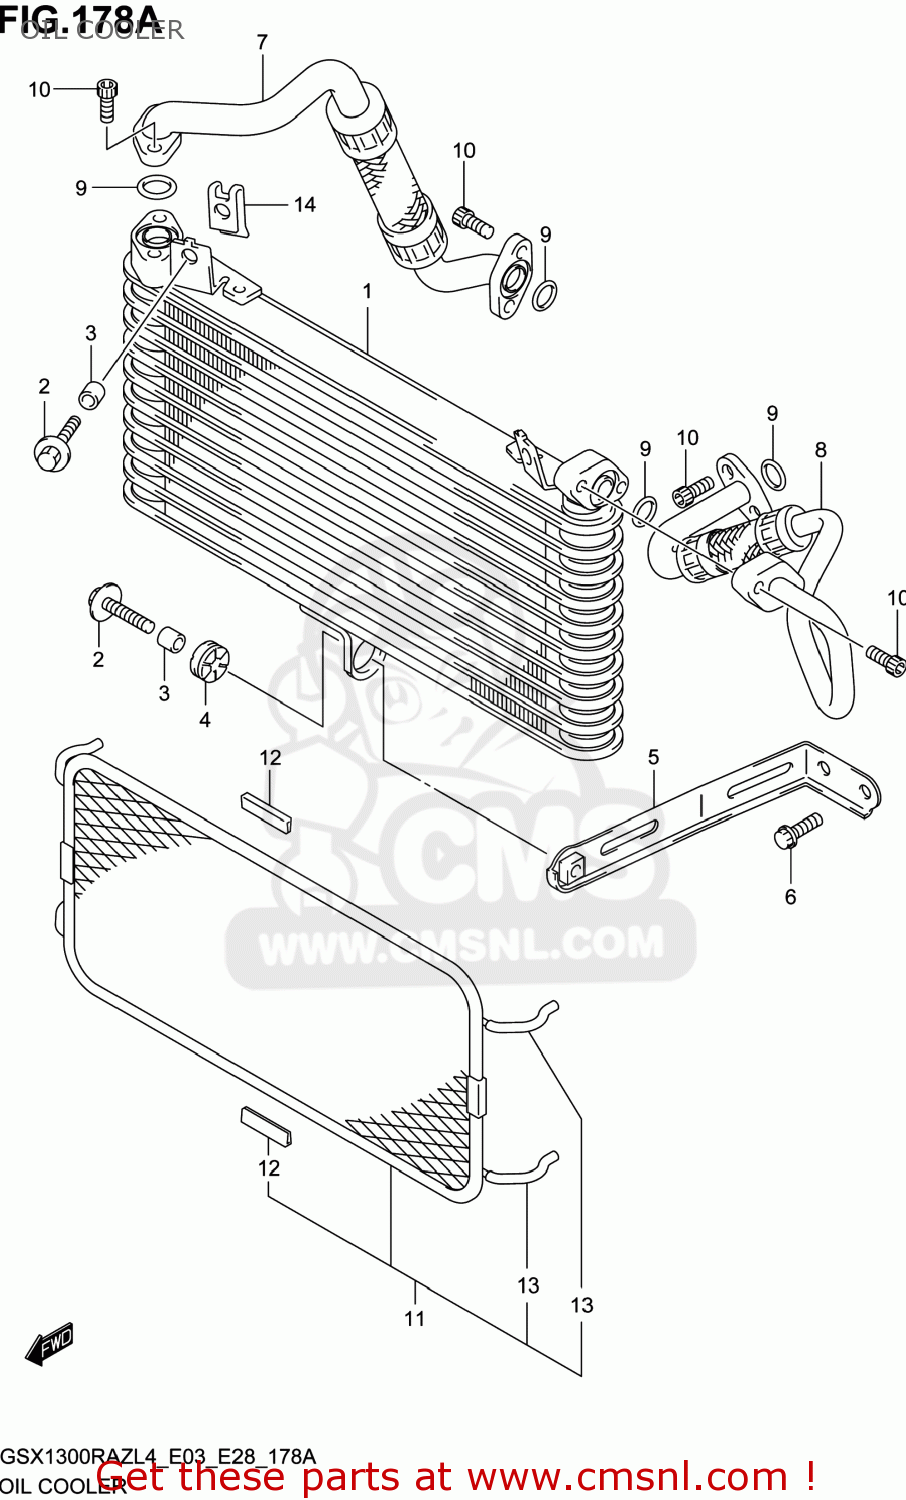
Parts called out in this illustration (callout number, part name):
1	COOLER ASSY,OIL
2	BOLT(6X25)
3	SPACER(6.5X10X12)
4	CUSHION
5	BRACKET,OIL COOLER
6	BOLT
7	HOSE,OIL COOLER,R
8	HOSE,OIL COOLER,L
9	O RING(D:2.4,ID:16)
10	BOLT(6X16)
11	GUARD,OIL COOLER
12	PROTECTOR,CTR
13	HOSE(3X5X600)
14	NUT,RADIATOR FAN
